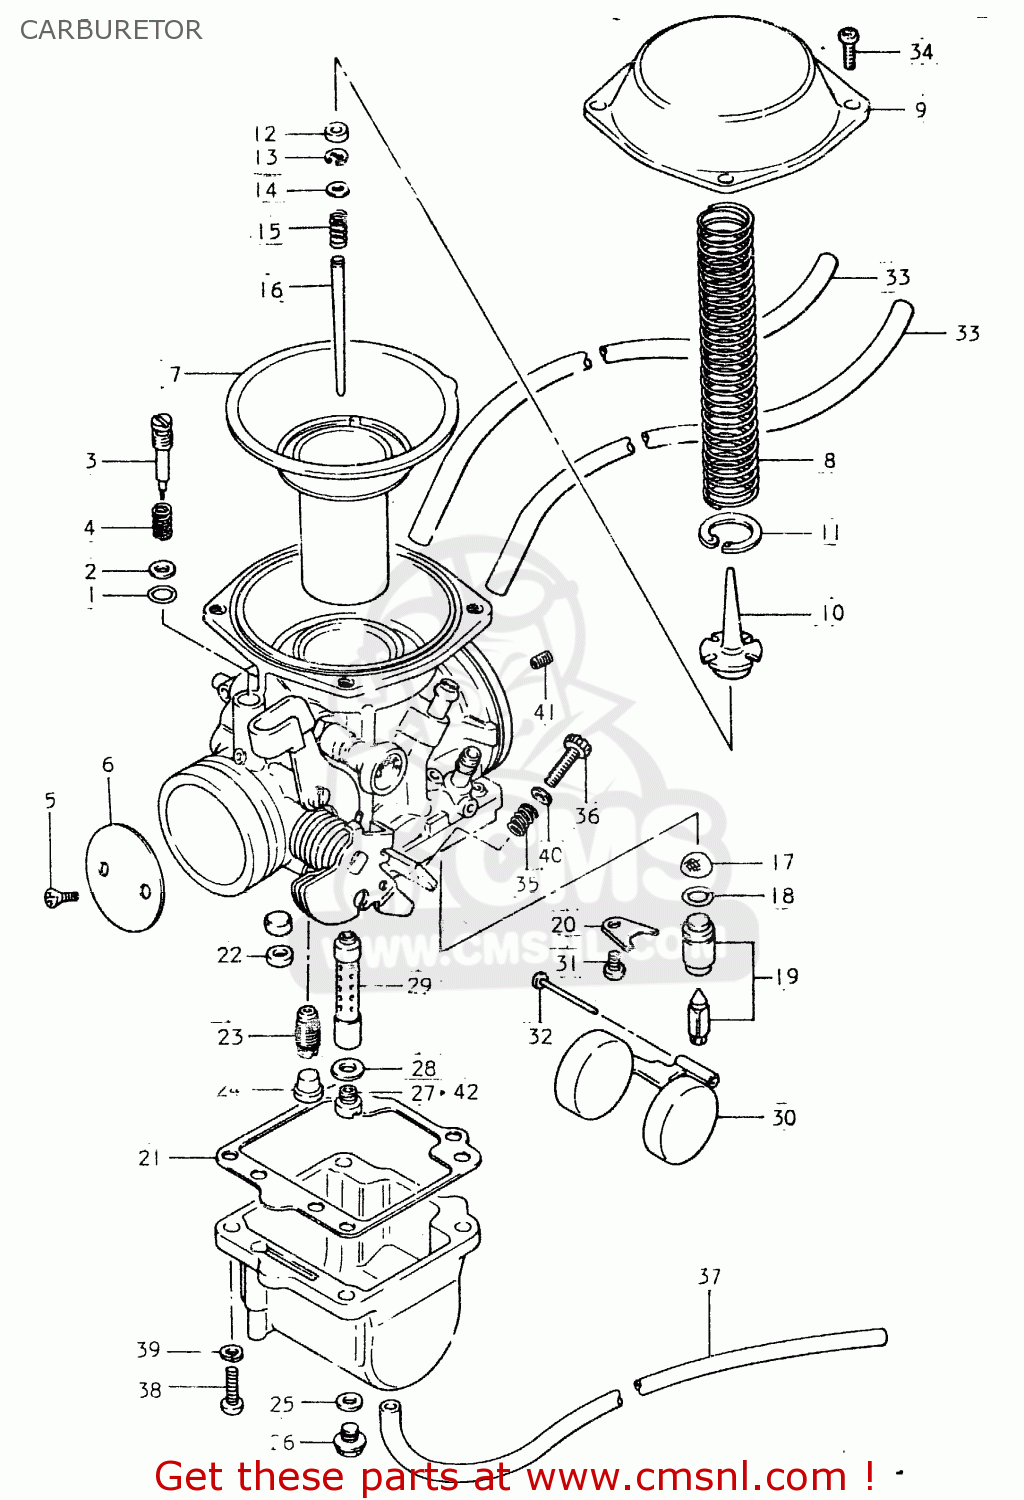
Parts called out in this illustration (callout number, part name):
1	O-RING
2	GASKET
3	SCREW, PILOT
4	SPRING
5	SCREW
6	VALVE,THROTTLE (BUTTERFLY)
7	DIAPHRAGM
8	SPRING
9	COVER,DIAPHRAGM
10	HOLDER,GUIDE
11	E RING
12	RING
13	CLIP,NEEDLE
14	WASHER
15	SPRING
16	NEEDLE, JET (5C35-3)
17	FILTER
18	O RING
19	VALVE ASSEMBLY,NEEDLE
20	PLATE
21	GASKET,FLOAT CHAMBER (NAS)
22	GASKET (NAS)
23	JET, PILOT (42.5)
25	GASKET (NAS)
26	PLUG,DRAIN
27	JET
28	WASHER
29	JET, NEEDLE (Y-6)
30	FLOAT
31	SCREW 4X6
32	PIN,FLOAT
33	HOSE
34	SCREW
35	SPRING,THROTTLE SHAFT
36	SCREW,THROTTLE STOP
37	HOSE
38	SCREW
39	LOCK WASHER
40	WASHER
41	JET
42	JET
